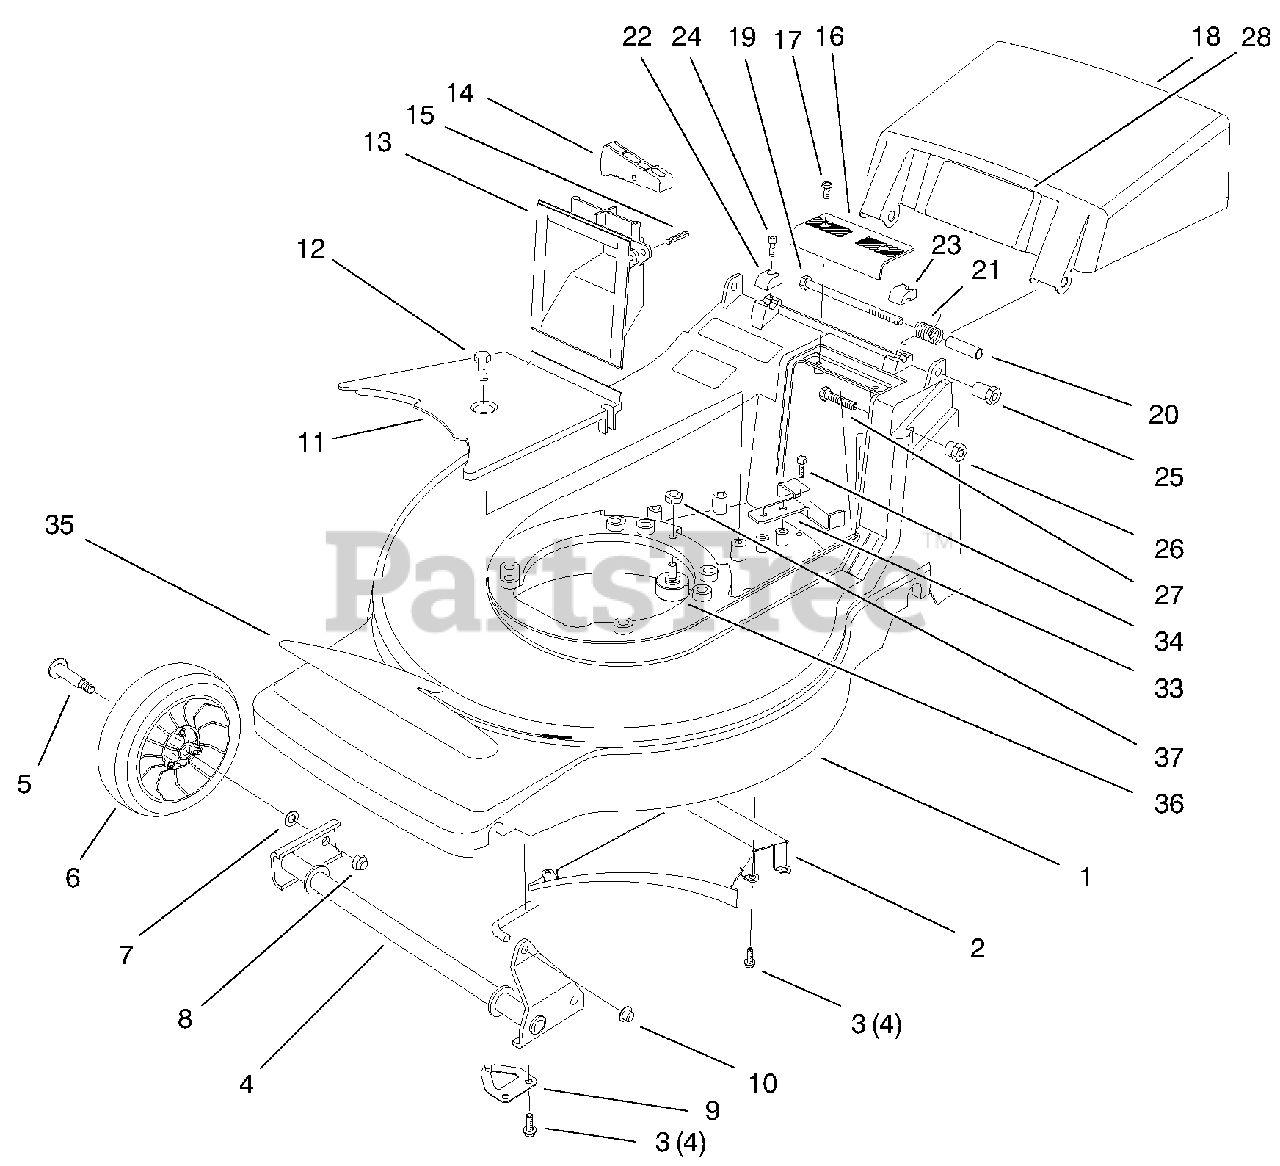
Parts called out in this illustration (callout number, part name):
1	Housing-Deck (Incl. Ref. # 35)
2	Ramp-Discharge
3	Screw-HH Tap
4	Pivot-Front
5	Bolt-Wheel
6	Wheel & Tire Assembly
8	Nut-Lock
9	Shaft Retainer Assembly
10	Nut-Push
11	Cover-Belt
12	Screw-Tap
13	Grip-Lower
14	Trigger-Hoc
15	Pin-Groove
16	Grip-Upper
17	Screw-PPH
18	Door-Discharge (Incl. Ref. # 28)
19	Screw-HH
20	Spacer-Door
21	Spring-Door
22	Cap-Bolt Hinge (RH)
23	Cap-Bolt Hinge (LH)
24	Screw-Thread Forming
25	Spacer-Handle
26	Spacer-Handle
27	Screw-HH
28	Decal-Danger
33	Guide-Belt Rear
34	Screw-HH Tap
35	Decal-Deck
36	Ball-Bearing, Stud
37	Nut-Hex Lock
